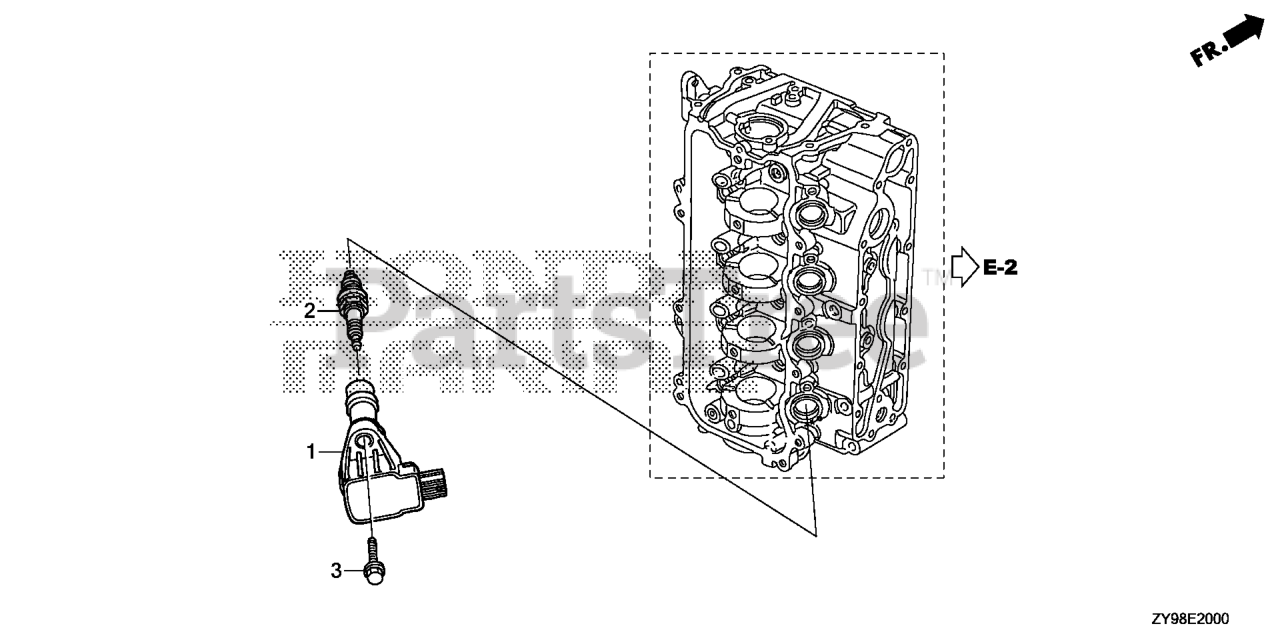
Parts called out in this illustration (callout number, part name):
1	COIL ASSY., PLUG TOP
2	SPARK PLUG (ZFR6K-9E) (NGK)
2	SPARK PLUG (IZFR6K-11E) (NGK)
3	BOLT, FLANGE (6X25)
